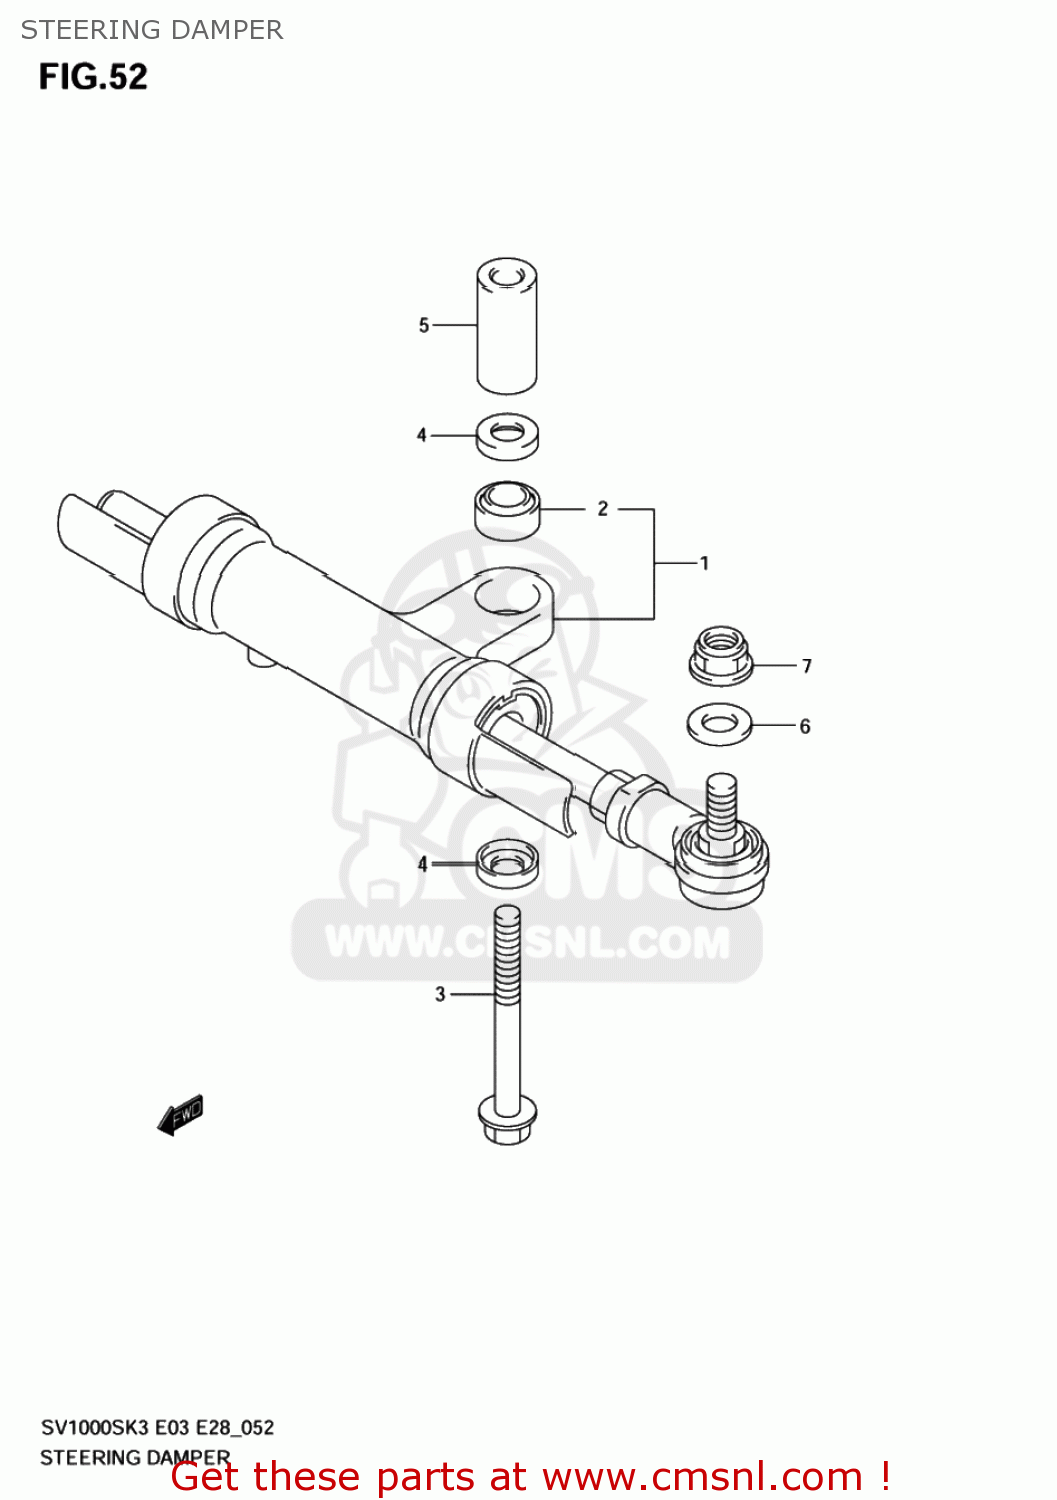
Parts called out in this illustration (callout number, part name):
1	DAMPER ASSY,STEERING
2	BEARING(8X17.5X11)
3	BOLT(8X65)
4	SEAL,PILLOW BALL,DUST
5	SPACER,STRG DAMPER
6	WASHER(8.5X18X1.6)
7	NUT
